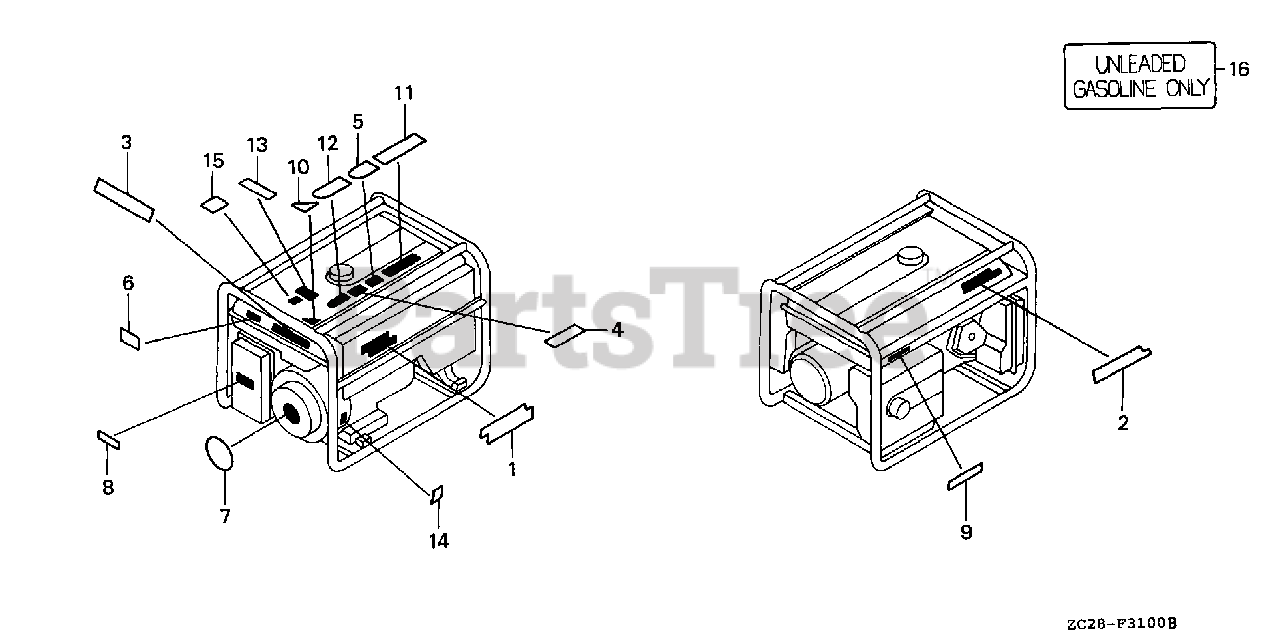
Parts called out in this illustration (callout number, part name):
1	MARK, EMBLEM (EW)
2	MARK, HONDA
3	PLATE, CAUTION
4	LABEL, RAIN WARNING (ENGLISH)
5	MARK, CAUTION (ENGLISH/FRENCH)(SPANISH)
6	MARK, CHOKE
7	MARK, OIL ALERT
8	MARK, AIR CLEANER
9	MARK, EX. CAUTION (ENGLISH/FRENCH)
11	MARK, CAUTION (CO)(ENGLISH/FRENCH)(SPANISH)
12	LABEL, CONNECT WARNING (ENGLISH)
13	MARK, FUEL METER
14	MARK, OIL CAUTION
